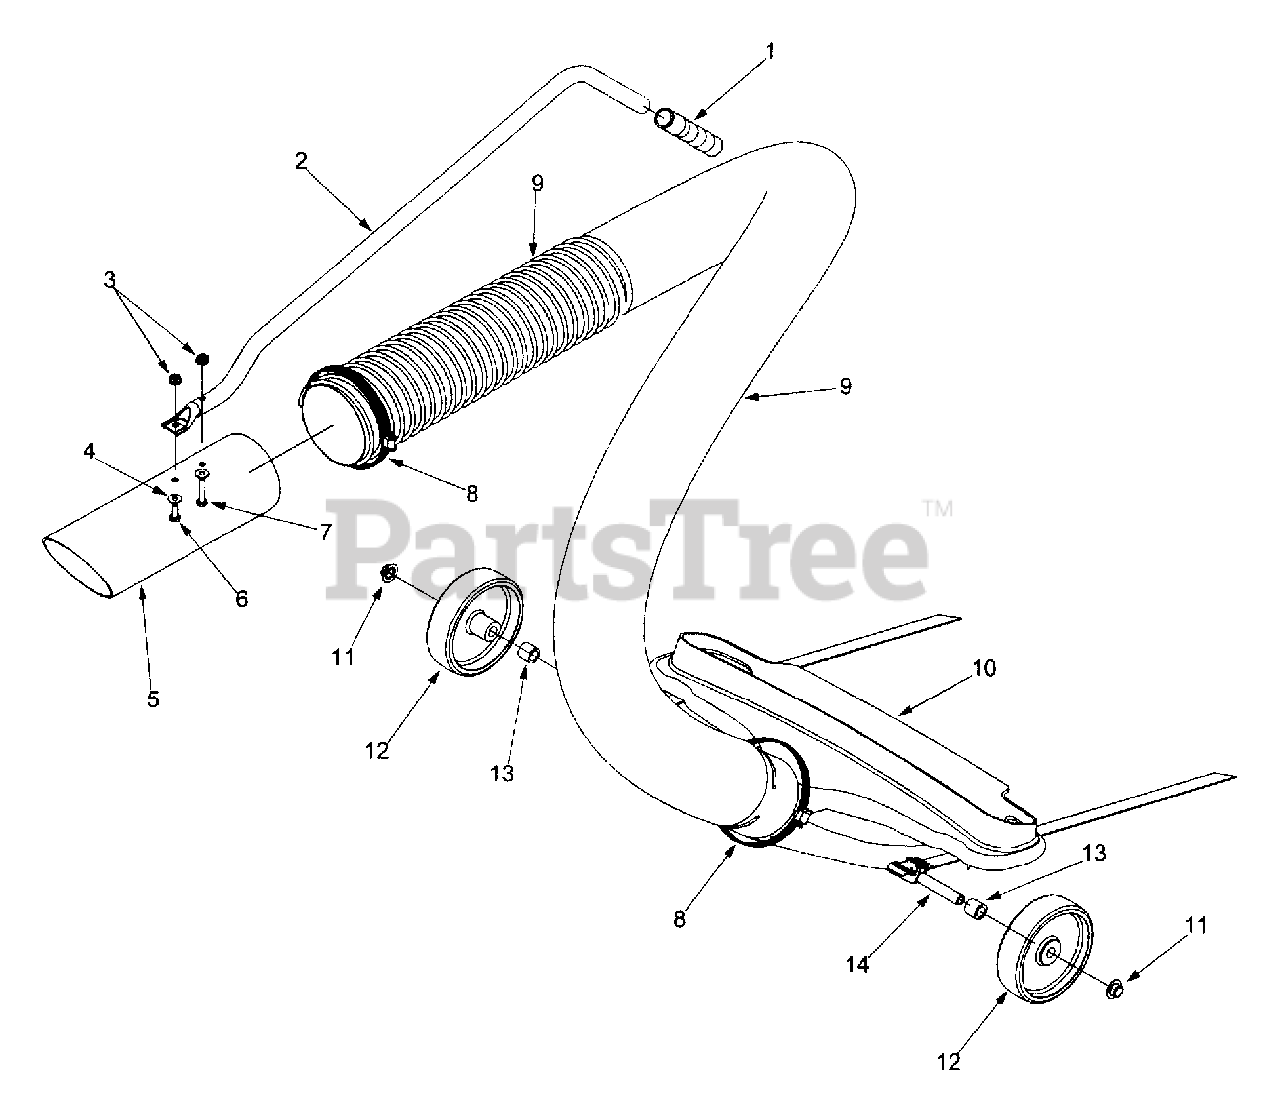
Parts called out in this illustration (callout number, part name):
1	Handle Grip
3	Hex Lock Nut 1/4-20
4	Flat Washer.271 ID x .630 OD
5	Nozzle 3.875 x 12.0
6	Hex Cap Screw 1/4-20 x .620
7	Hex Cap Screw 1/4-20 x 1.25
8	Adjustable Clamp
9	Vacuum Hose
10	Hose Attachment Nozzle Ass'y
11	Push Cap
12	Wheel 5.0 x 1.38
13	Spacer
14	Axle .50 OD x .354 ID x 16.7
